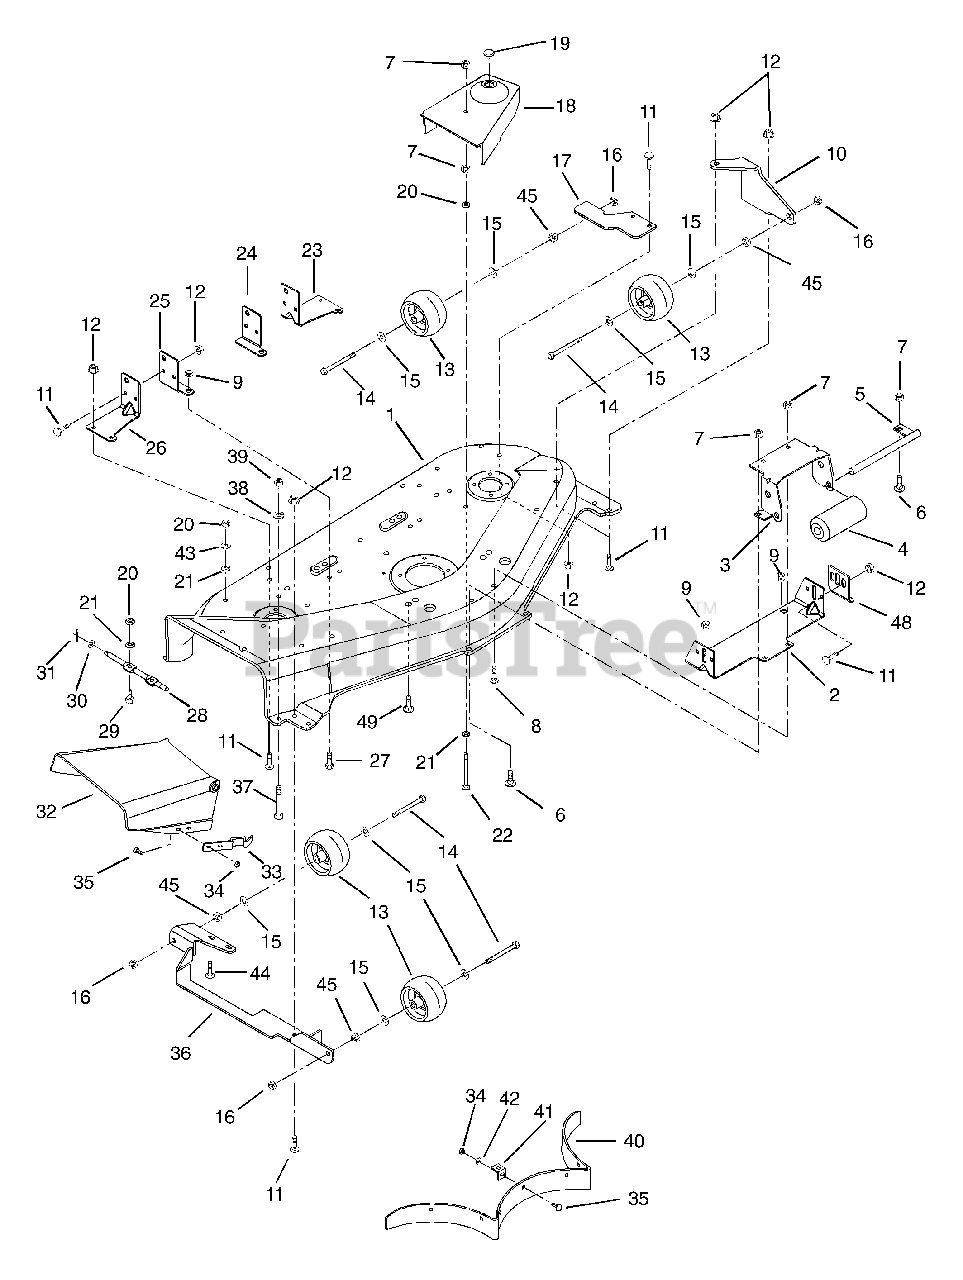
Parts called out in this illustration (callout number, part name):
1	48" DECK W/DECALS - GLT
2	FRONT HANGER
3	BRACKET, ROLLER
5	ROLLER SHAFT
6	@BLT-RDHDSQNK .31-18X.75 G5YZ
7	@NUT-LK-CTR .31-18 YWZC
8	@BLT-RHDSSQNK .31-18X.62 G5YZ
9	@NUT-LK-CTR .50-13 YWZC
10	BRACKET - LEFT FRONT
11	BLT-RDHDSQSHK.31-18X.75 GR2 YW
12	@NUT-SPNLK-FLG .312-18 YWZC
13	WHEEL 5 X 3
14	@BLT-HEX .50-13X4.50 GR5 YWZC
15	WSHR-FL-NYL .518X1.000X.080
16	@NUT-LK-CTR .50-13 YWZC
17	BRACKET, LEFT REAR - RED
18	COVER, RIGHT HAND
18	COVER, LEFT HAND
19	BUTTON PLUG 1.0
20	@NUT-HEX .31-18 YWZC
21	WSHR-LK .312X.097 HVY YWZC
22	BLT-RDHDSQNK .31-18X3.25 SHTPL
23	LH REAR HANGER - RED
24	LH REAR HANGER SUPPORT
25	RH REAR HANGER SUPPORT
26	RH REAR HANGER - RED
27	@BLT-HEX .50-13X1.00 GR5 YWZC
28	HINGE PIN
29	@BLT-HEX .31-18X.75 GR5 YWZC
30	@WSHR-FL-STL.406X.812X.065 YWZ
31	@PIN-CTR .09X.75 EXTPRSQCT YWZ
32	CHUTE EXTENSION
33	FLAT SPRING - RED
34	@NUT-LK-CTR .25-20 YWZC
35	BLT-RDHDSQSHNK.25-20X.50 YWZC
36	MOUNT - ROLLER
37	@BLT-HEX .38-16X2.50 GR5 YWZC
38	WSHR-LK .375X.115 HVY YWZC
39	@NUT-HEX .38-16 YWZC
40	BAFFLE
41	BAFFLE TAB
42	@WSHR-FL-STL.281X.62X.065 YWZC
43	@WSHR-FL-STL.312X.734X.065 YWZ
44	@BLT-RDHDSQNK .31-18X1.00 G5YZ
45	@NUT-LK-CTR .50-13 YWZC
46	GUARD - FOOT - LEFT - RED
47	GUARD - FOOT - RIGHT - RED
48	MOWER ADJUSTMENT TAB
49	@BLT-RDHDSQNK .50-13X1.00 G2YW
